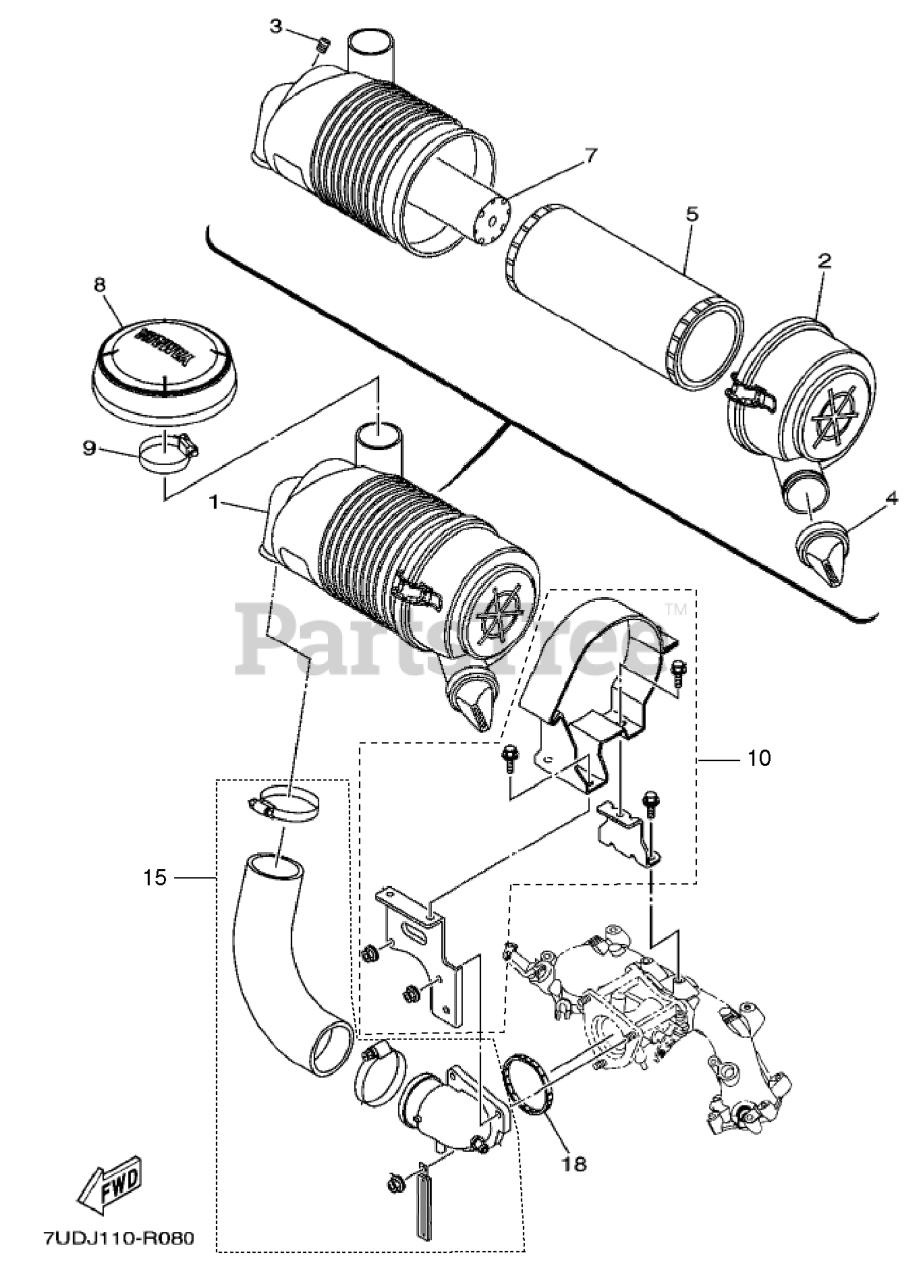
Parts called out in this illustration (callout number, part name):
1	AIR CLEANER ASSY YAMAHA PN: 7U
2	CAP CLEANER CASE 1 YAMAHA PN:
3	PLUG YAMAHA PN: 7UD-E432A-00
4	PLUG BLIND YAMAHA PN: 7UD-E443
5	AIR FILTER OUTER ELEMENT YAMAH
7	AIR FILTER INNER ELEMENT YAMAH
8	COVER AIR RAIN CAP YAMAHA PN:
9	HOSE CLAMP ASSY YAMAHA PN: 904
10	PLATE KIT INTAKE STAY KIT
15	JOINT INTAKE JOINT KIT
18	SEAL YAMAHA PN: 7UD-E4452-00
